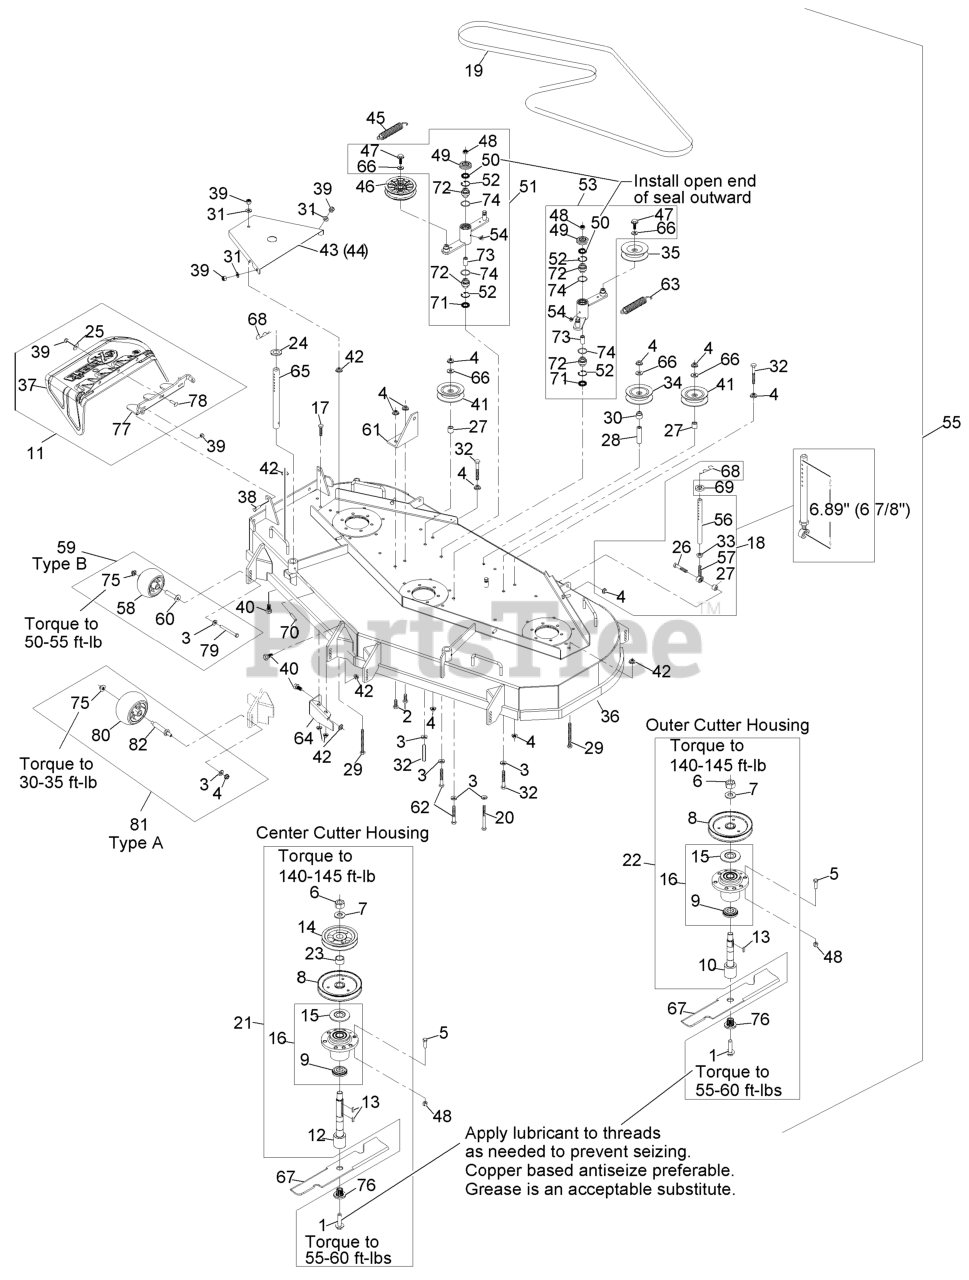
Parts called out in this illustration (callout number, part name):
1	SCREW,SEMS 1/2-20 X 2.19
2	SCREW-HH
3	WASHER-BELLEVILLE
4	NUT-HHF, WHIZ
5	SCREW-HH
8	SHEAVE,BLADE DRIVE 6.30
9	SPACER-GUARD, BOTTOM
10	KIT, SPLINED SPINDLE 103-
11	ASM,FMD DISCHARGE CHUTE
12	KIT, SPLINED SPINDLE 103-
14	SHEAVE,BLADE DRIVE
15	GUARD-BEARING, TOP
16	KIT, CUTTER HOUSING
17	SCREW-HH
18	KIT,SUPPORT LINK W/PIN
19	BELT,MULE DRIVE
20	SCREW-HH
21	ASM, CUTTER HSG FMD604CTR
22	ASM, CUTTER HSG COMPLETE
23	SPACER,TUBE
24	SPACER-DECK SUPPORT
25	WASHER-FLAT
26	SCREW-HH
28	SPACER-ANCHOR, CLUTCH
29	BOLT,TAP HH
30	BUSHING,IDLER
31	WASHER-FLAT
32	BOLT-CARR
33	NUT-HJ
34	PULLEY-IDLER
35	PULLEY-IDLER
36	ASM, DECK W/ DECALS FMD60
37	CHUTE,DISCHARGE
38	SCREW-HH
39	NUT-LOCK, NI
40	SCREW-HH
41	IDLER,PULLEY
43	SHIELD,BELT RH
44	SHIELD,BELT LH
45	SPRING-EXTENSION
46	PULLEY-IDLER, FLAT
47	SCREW-HHF
48	NUT-LOCK, NI
49	GUARD-TOP
50	SEAL-LIP, SINGLE
51	KIT, IDLER ARM W/BEARINGS
52	RING-SNAP
53	KIT, IDLER ARM W/BEARINGS
54	FITTING-GREASE, 90 DEG
55	Complete Deck Assy
56	LINK,SUPPORT
57	BALLJOINT
58	ROLLER-SCALP, ANTI
59	KIT, ANTI-SCALP ROLLER
60	AXLE, ROLLER
61	BRACKET,SPRING ANCHOR
62	SCREW-HH
63	SPRING-EXTENSION
64	BAFFLE,DISCHARGE
65	ROD,DECK SUPPORT
66	WASHER-FLAT
68	PIN,HAIR COTTER
71	SEAL-LIP, DOUBLE
72	BEARING-SPHERICAL
73	BUSHING-LEVER, LIFT
75	Nut-Nyloc 3/8-16 Flg
76	BUSHING,SPLINED
77	BRACKET, DISCHARGE CHUTE
78	SCREW-CARR
79	SCREW-HH 3/8-16 X 3 3/4 GR 8
80	ROLLER-SCALP, ANTI
